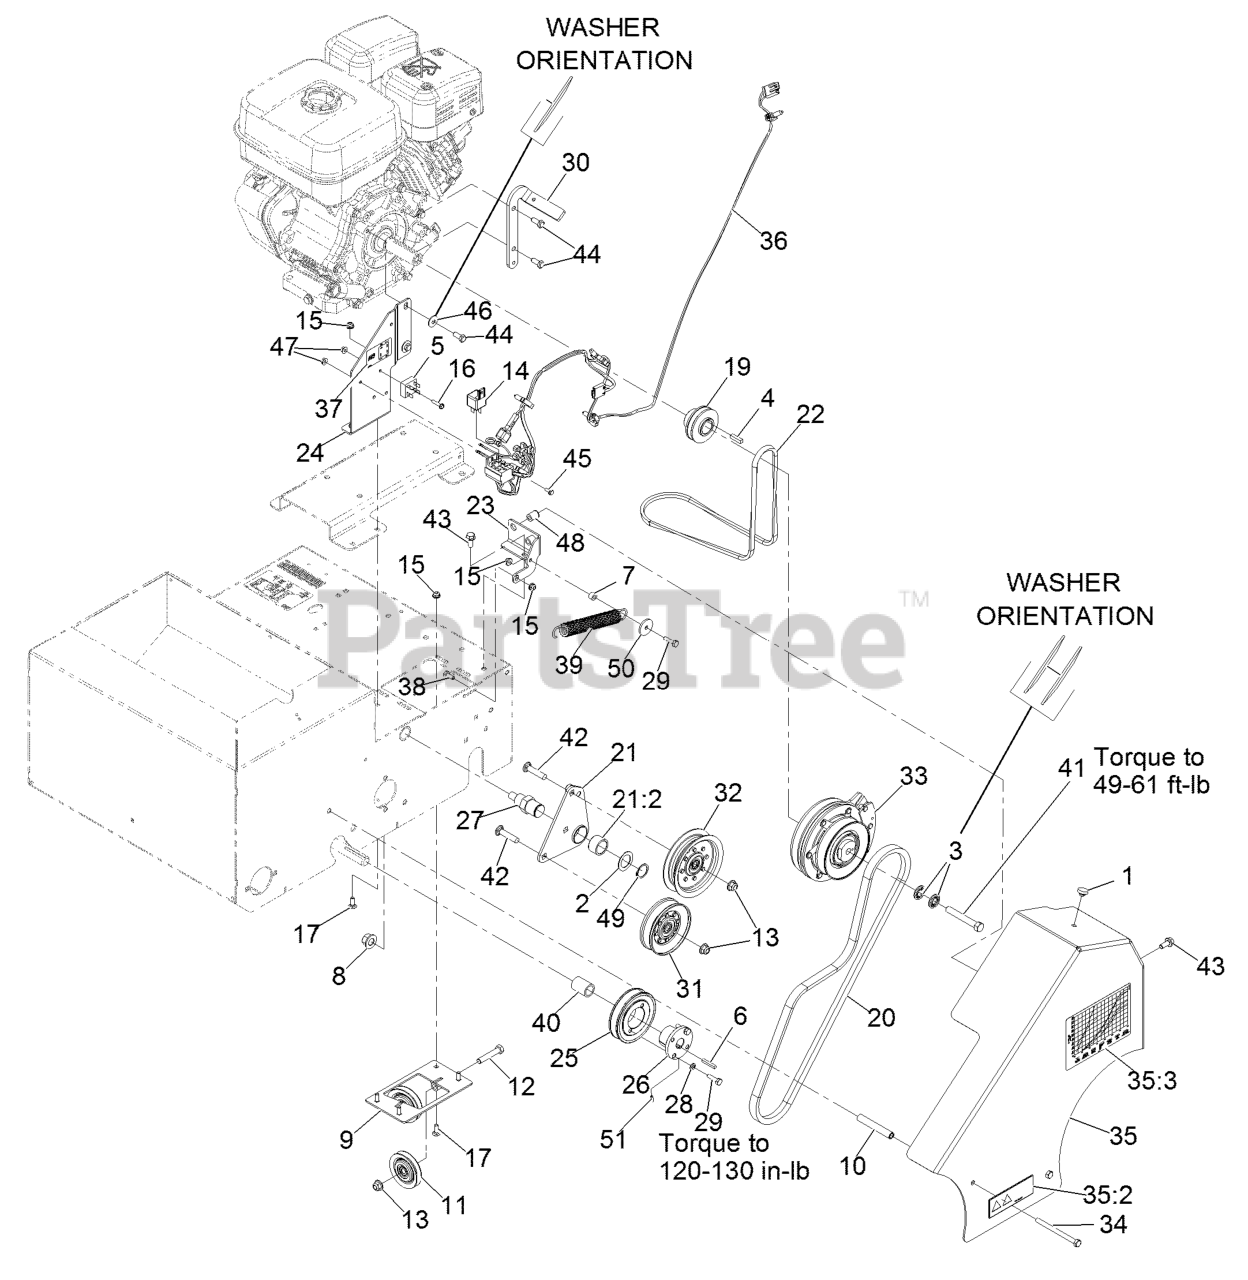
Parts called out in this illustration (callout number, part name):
2	WASHER-SPACER
3	WASHER-SPRING
5	RECTIFIER-BRIDGE
6	KEY-SQUARE
8	Nut-Lock 1/2-13
9	PULLEY-TENSION
10	SPACER-KICKSTAND, LONG
11	PULLEY-IDLER
12	SCREW-HH
13	NUT-HF, NI
16	SCREW-HWH
17	BOLT-CARR
19	PULLEY-MULE DRIVE
20	BELT-SEEDER, CLUTCH
21	IDLER ARM ASM
21:2	BUSHING
22	BELT-MULE DRIVE
23	BRACKET-SPRING
24	SUPPORT-ENGINE
26	BUSHING-TAPER LOCK
27	PIVOT-IDLER
28	SCREW-HH
29	SCREW-HH
30	STOP-CLUTCH
31	PULLEY-IDLER V
32	PULLEY-IDLER FLAT (4.06-I
33	CLUTCH-ELECTRIC
34	SCREW-HH
35	BELT GUARD ASM
35:2	DECAL-DANGER
35:3	DECAL-GRAPH, SEED
36	HARNESS-SLICER/SEEDER
37	Decal-Bridge Rectifier
38	SCREW-HH
39	SPRING-EXTENSION
41	SCREW-HH
42	SCREW-CARR
43	SCREW-HHF
44	SCREW-HH
45	SCREW-HWH
46	WASHER-BELLEVILLE
47	NUT-LOCK, FLANGE
48	NUT-CLINCH
49	RING-RETAINING
50	WASHER
51	SCREW-SET, HS
